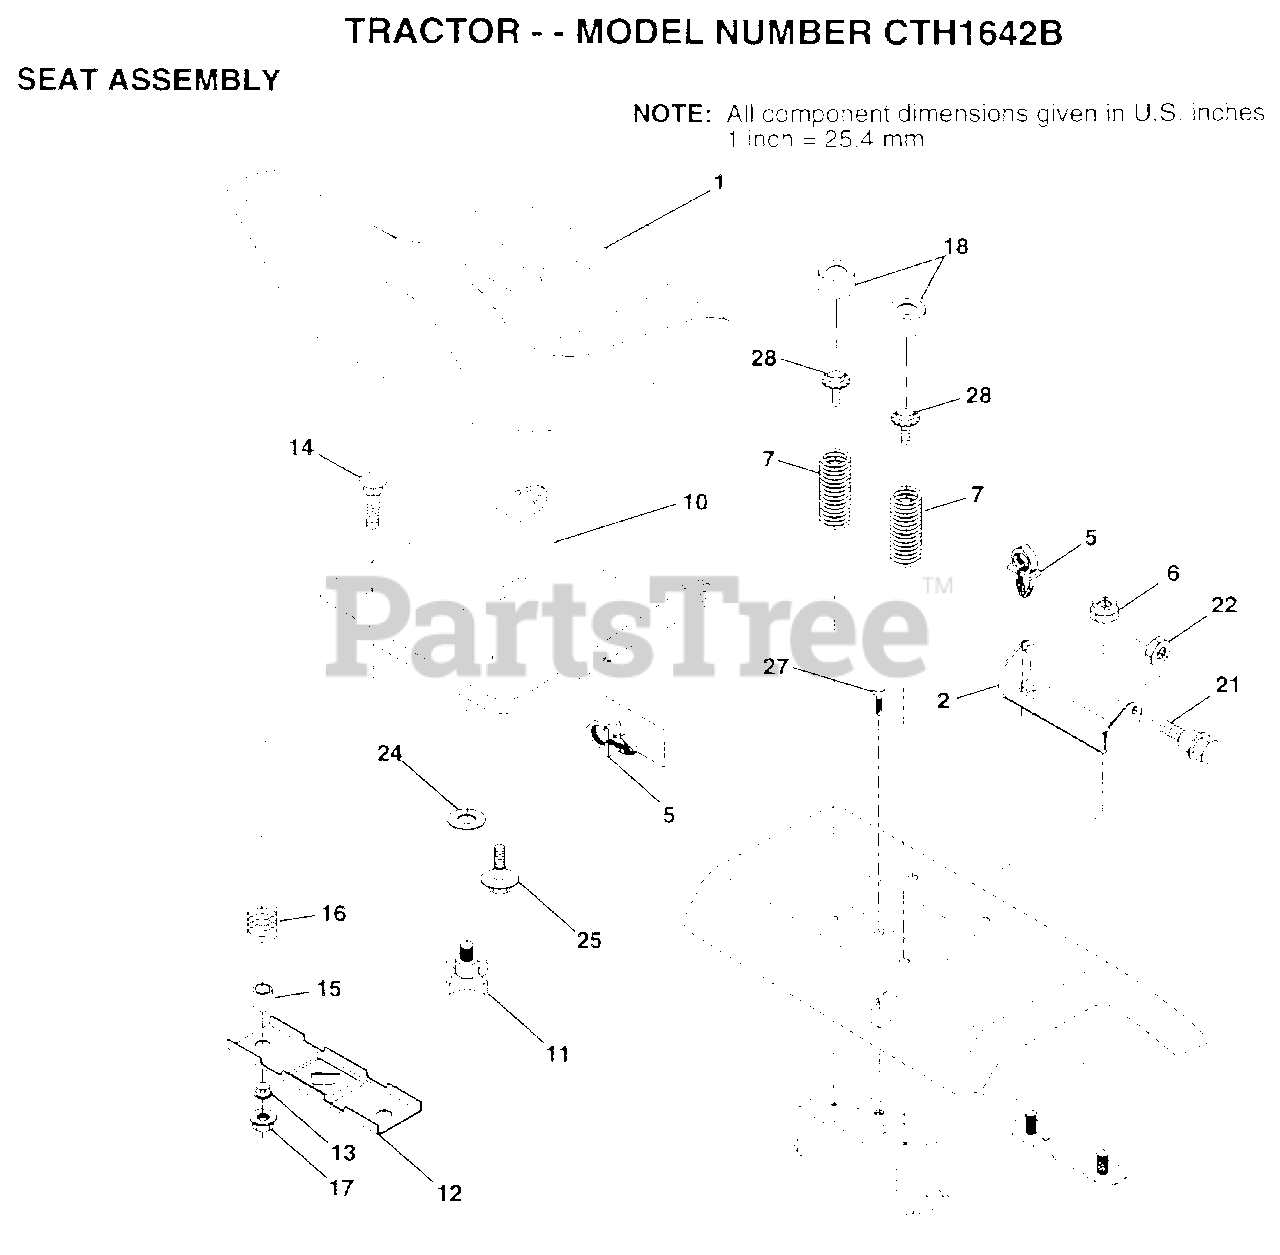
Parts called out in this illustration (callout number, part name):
2	BRACKET PVT SEAT
5	CLIP.PUSH-IN.HING
6	NUT
7	SPRING COMPRESSIO
8	SCREW LT
9	WASHER
11	"KNOB 1/2"" YT"
12	BRKT SWITCH
13	BUSHING
15	SPACER SPLIT
16	SPRING COMPRESSED
18	CAP SPRING
21	BOLT.SHLD.5/16-18
24	WASHER
25	"BOLT,SHOULDER"
27	SCREW LT
28	BOLT.5/16-18.UNC
